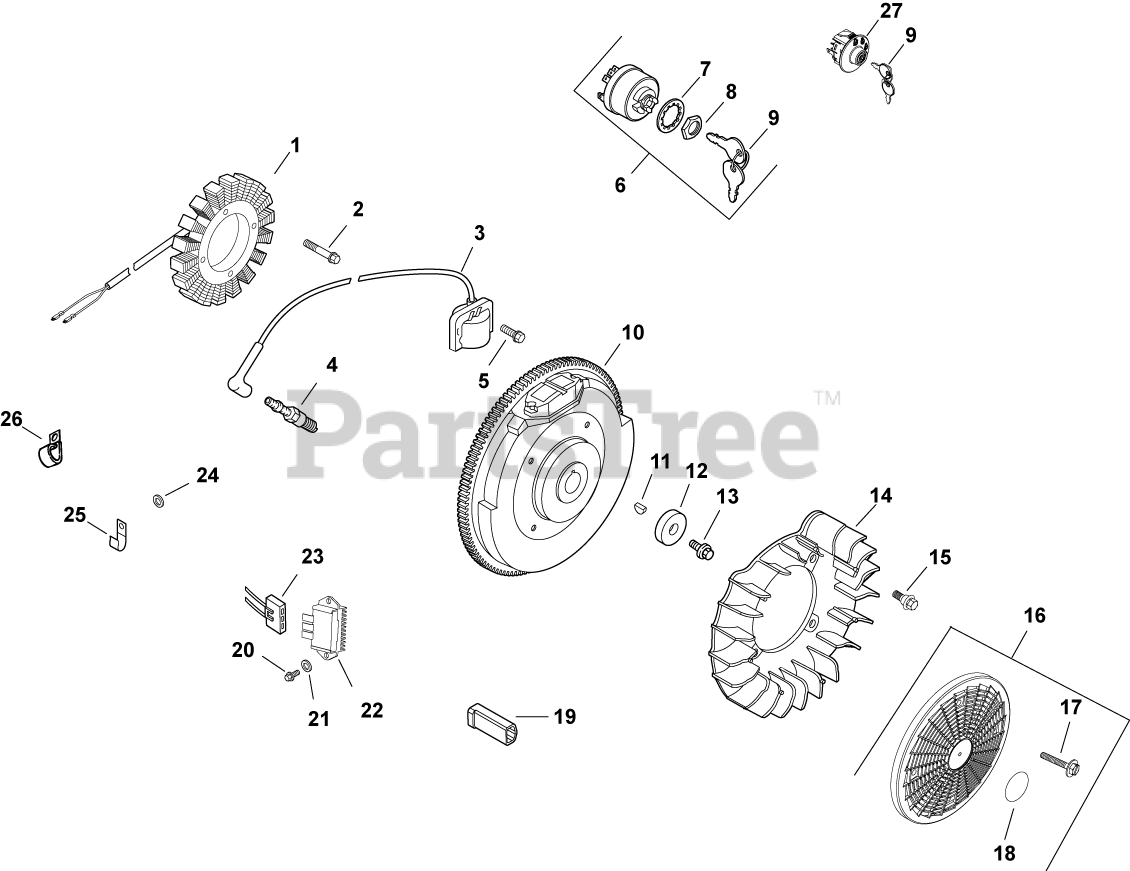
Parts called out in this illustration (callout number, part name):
1	KIT, 15 / 20 AMP STATOR
2	SCREW, M5X0.8X25 - (#25086402S)
3	KIT, MODULE IGNTN (CDI FIXED)
4	PLUG, SPARK (PRO SERIES)
5	SCREW, SKT THD FRM M5X0.8X25
6	SWITCH ASSY, KEY (KM)-USE 25 099 32-S
7	WASHER, INTERNAL TOOTH
8	NUT, KEY SWITCH
9	KEY, SET -USE 48 340 01-S
10	FLYWHEEL, PAINTED-USE 24 025 55-S
11	KEY, 3/16" X 5/8"
12	WASHER, FLAT 13/32"
13	SCREW, FLG M10X1.5X45 - (#25086361S)
14	FAN USE 24 755 253-S
15	BOLT, SHOULDER
16	KIT, GRASS SCREEN
17	SCREW, FLG SEMS M4X.7X25
18	DECAL, GRASS SCREEN USE 24 113 499-S
19	CONNECTOR (1 CONTACT)
20	SCREW, PHL HD #11-16X7/8"
21	WASHER, FLAT 3/16"
22	REG/RECTIFIER (20/25 AMP)-USE 25 403 20-
23	CONNECTOR, BODY (KM)-USE 25 155 41-S
24	WASHER, FLAT 1/4" (O.D. 1/2")
25	CLIP, CABLE
26	CLIP, TUBE & WIRING (KM)
27	KIT, KEY SWITCH (SNAP-IN)
